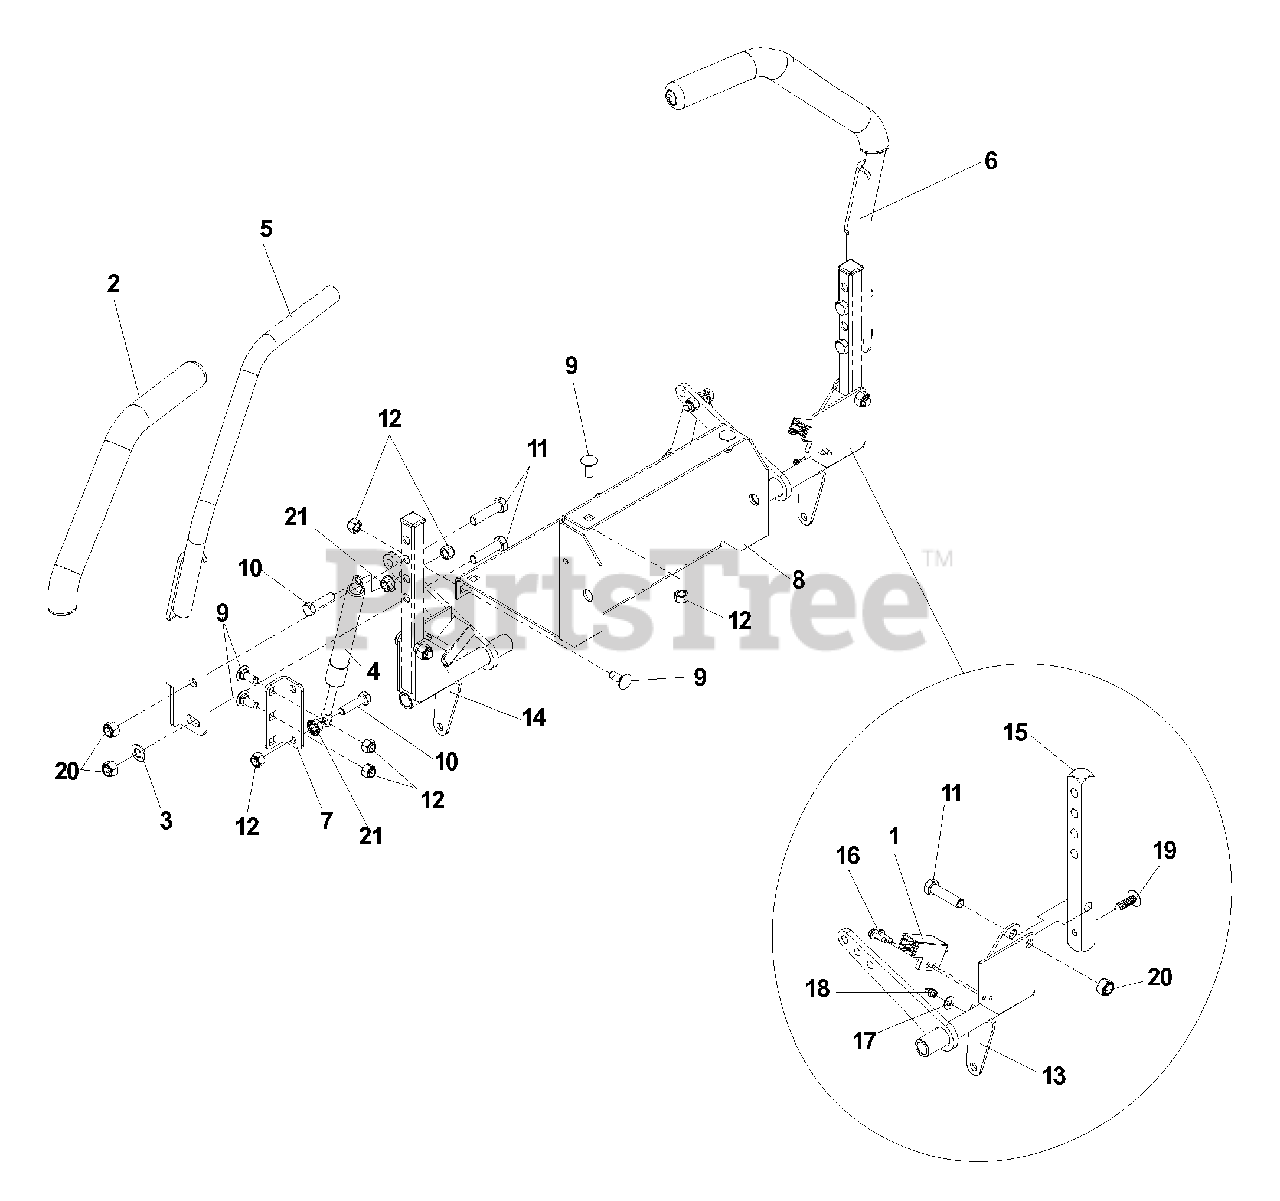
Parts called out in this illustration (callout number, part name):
1	SWITCH, INTERLOCK
2	CUSHION, DRIVE LEVER
3	LOCKWASHER, 3/8, SPEC.
5	DRIVE LEVER, RIGHT
6	DRIVE LEVER, LEFT
7	DAMPENER BRACKET
8	BATTERY TRAY
9	RHSNB, 5/16-18 X 3/4, GR5
10	HCS, 5/16-18 X 1 1/4, GR5
11	HCS, 3/8-16 X 1 1/2, GR5
12	NUT, 5/16-18, NYLOC
13	CONTROL WELDMENT, LEFT
15	CONTROL ARM
16	SCREW, 10-24 X 5/8, WASHER HD
18	ZERK
19	RIVET, NYLON PUSH-IN
20	NUT, 3/8-16, NYLOC
21	NUT, 5/16-18, WHIZLK
